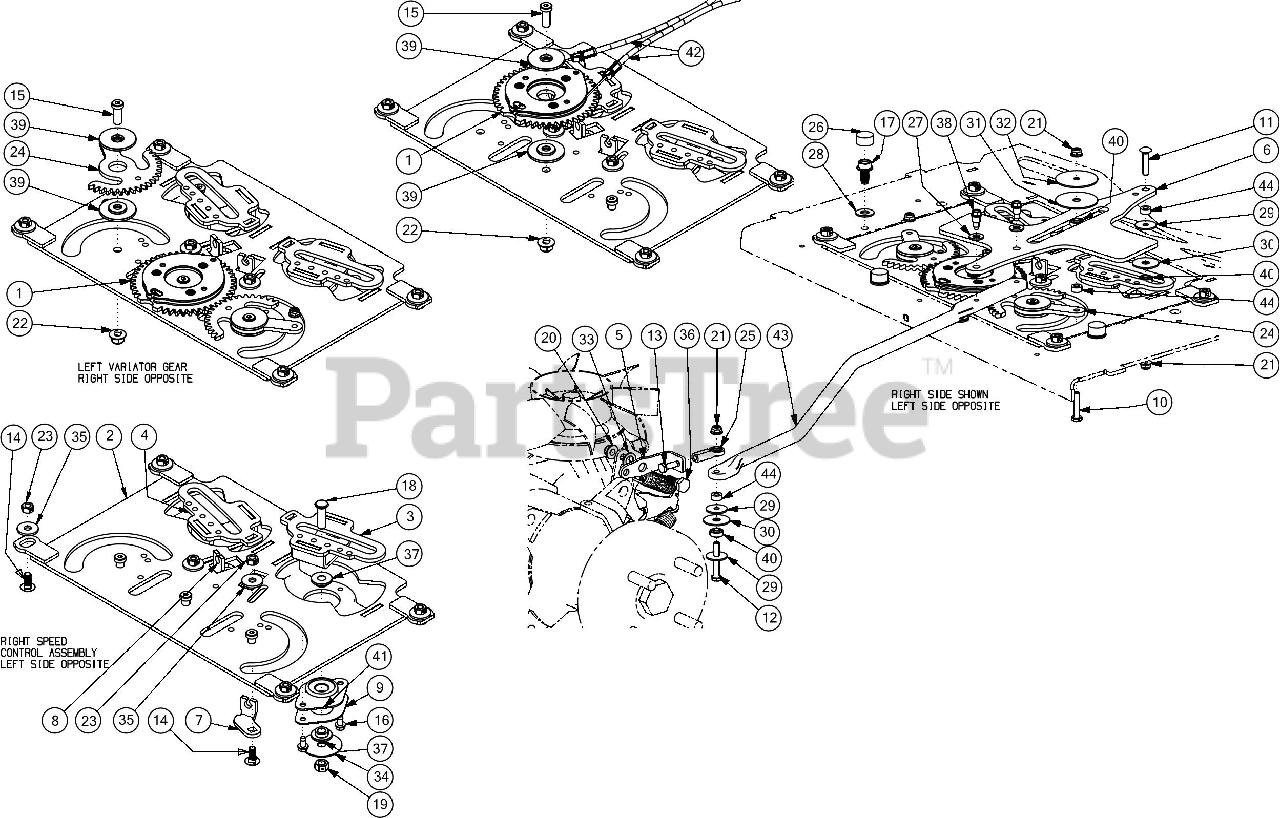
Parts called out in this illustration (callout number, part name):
1	PUMP GEAR
2	CONTROL MOUNT PUMP PLATE
3	CONTROL PUMP CAM ASSEMBLY (RH)
4	CONTROL PUMP CAM ASSEMBLY (LH)
5	PUMP BRACKET
6	ACTUATOR PUMP ARM
7	STEERING CABLE BRACKET
8	CABLE CLAMP BRACKET
9	RETAINING PLATE
10	HEX SCREW 1/4-20 X 1.25
11	CARRIAGE BOLT 1/4-20 X 1.25 G
12	HEX SCREW 1/4-20 X 1.75
13	HEX SCREW 1/4-28 X .75
14	CARRIAGE BOLT 5/16-18 X .75
15	SCREW 3/8-16 X 1
16	SCREW 1/4-20 X.500
17	SCREW 3/8-16 X 3/4
18	SCREW 3/8-16 X 1.25 GR5
20	FLANGE LOCK NUT 5/16-18
21	FLANGE LOCK NUT
23	HEX NUT
24	STEERING GEAR YOKE
25	END ROD (RH)
26	SLIDE CAP
27	FLAT WASHER
28	FLAT WASHER
29	FLAT WASHER
30	WASHER .355X1.25X.06THK
31	FLAT WASHER
32	FLAT WASHER
33	FLAT WASHER .469X.750X.054
34	HUB CAP WASHER .406 X 1.92 X .060
35	FLAT WASHER .345X1.0X.100
36	SHOULDER SCREW .437
37	SHOULDER SPACER
38	SHOULDER SCREW
39	SHOULDER SPACER
40	BALL BEARING .25 X .625 SPCL
41	BALL BEARING
42	CONTROL CABLE
43	PUMP CONTROL ROD
